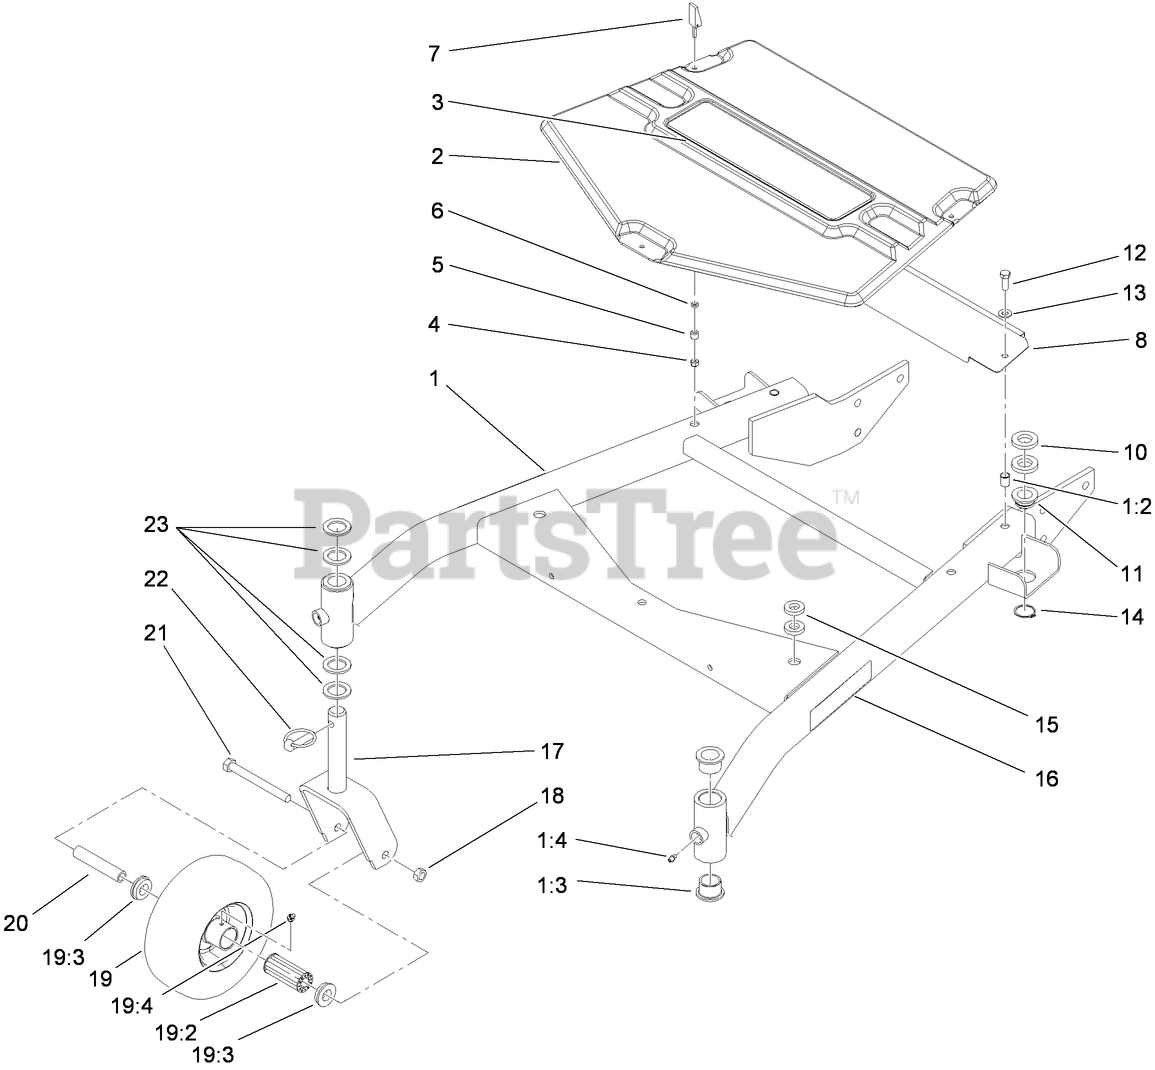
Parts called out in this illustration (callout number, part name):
1	CARRIER FRAME ASM
1:2	INSERT-NUT
1:3	BUSHING
1:4	FITTING-GREASE
2	COVER-FRAME, CARRIER
4	NUT-LOCK, HH
5	BUSHING-LATCH, SWELL
6	WASHER
7	HANDLE-LATCH, SWELL
8	SHIELD-BELT
10	SPACER-SUPPORT, DECK
11	BUSHING-DECK
12	SCREW-HH
13	WASHER-FLAT
14	RING-RETAINING
15	SPACER
16	DECAL-HOC
17	FORK-CASTOR
18	NUT-HEX
19	WHEEL AND TIRE ASM
19:2	BEARING-ROLLER
19:3	BUSHING
19:4	FITTING-GREASE
20	BUSHING-SPANNER
21	SCREW-HH
22	PIN-LYNCH
23	WASHER-THRUST
